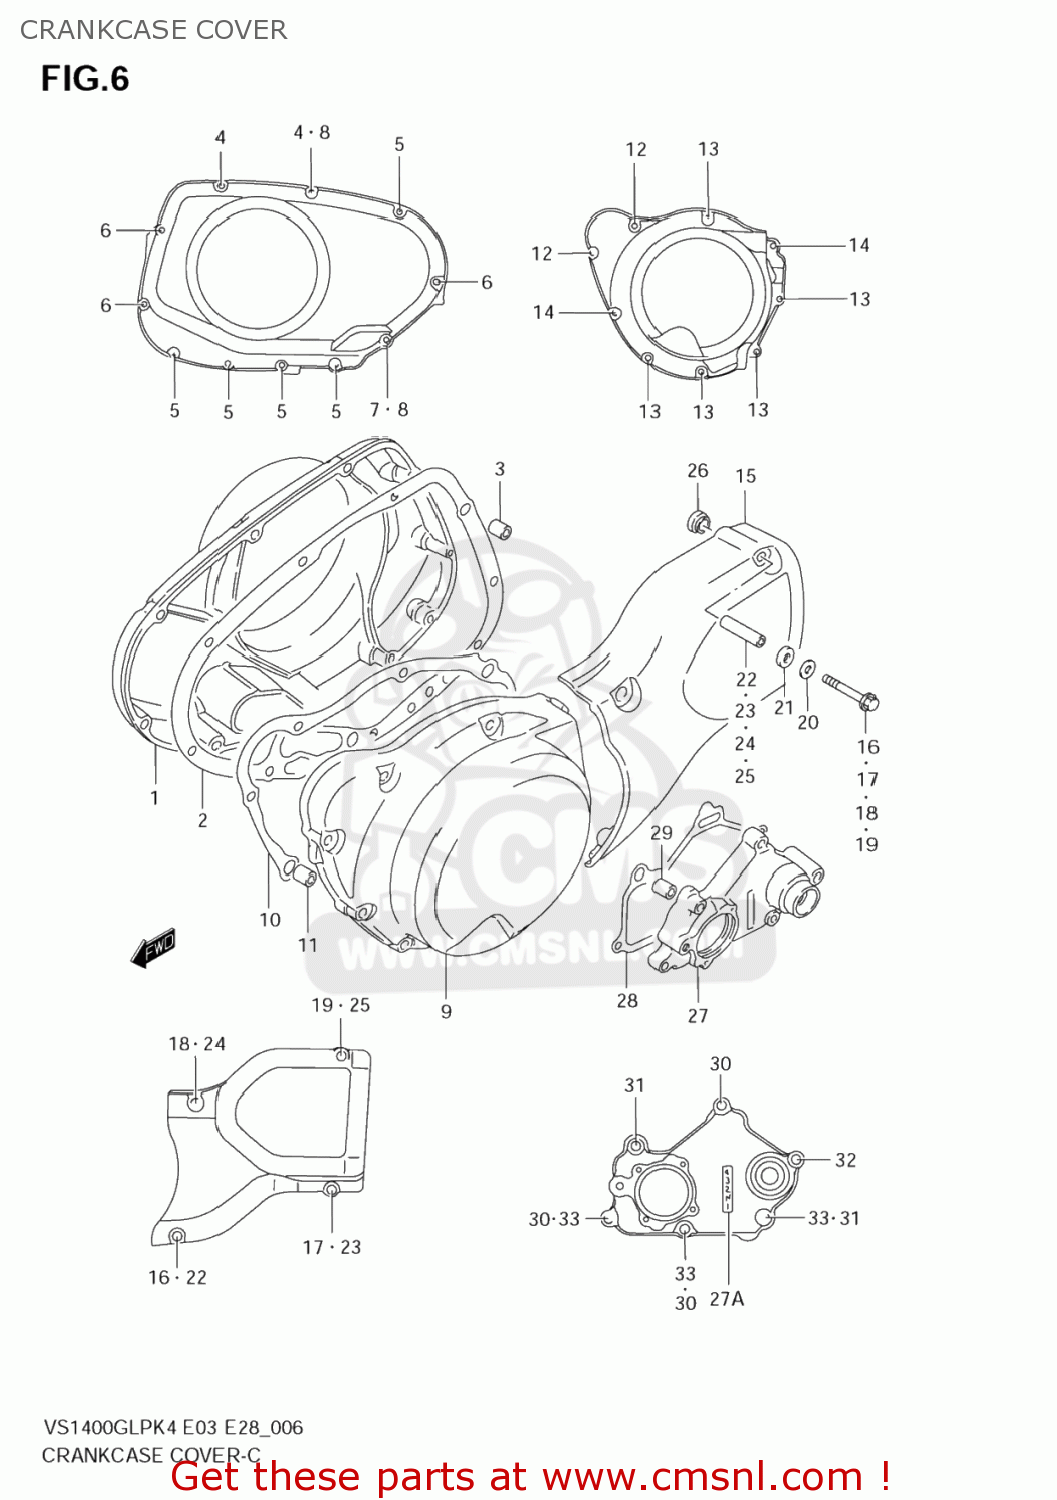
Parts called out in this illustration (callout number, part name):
1	COVER,CLUTCH
2	GASKET,CLUTCH COVER (NAS)
3	PIN
4	BOLT
5	BOLT
6	BOLT
7	BOLT
8	GASKET(5.8X13X1.2) (NAS)
9	COVER,GENERATOR
10	GASKET,GENERATOR COVER (NAS)
11	PIN(8.4X11X20)
12	BOLT
13	BOLT
14	BOLT
15	COVER,SECONDARY GEAR CASE
16	BOLT
17	BOLT
18	BOLT
19	BOLT
20	WASHER(6.5X14X1.6)
21	WASHER(8.7X16X5)
22	SPACER(6.5X9X21)
23	SPACER(6.5X9X26)
24	SPACER(6.5X9X49)
25	SPACER(6.5X9X45.9)
26	WASHER(8.7X16X5)
27	COVER,GEAR SHIFT
27A	LABEL,GEAR SHIFT
28	GASKET,GEAR SHIFT COVER (NAS)
29	PIN
30	BOLT
31	BOLT
32	BOLT
33	GASKET(5.8X13X1.2) (NAS)
